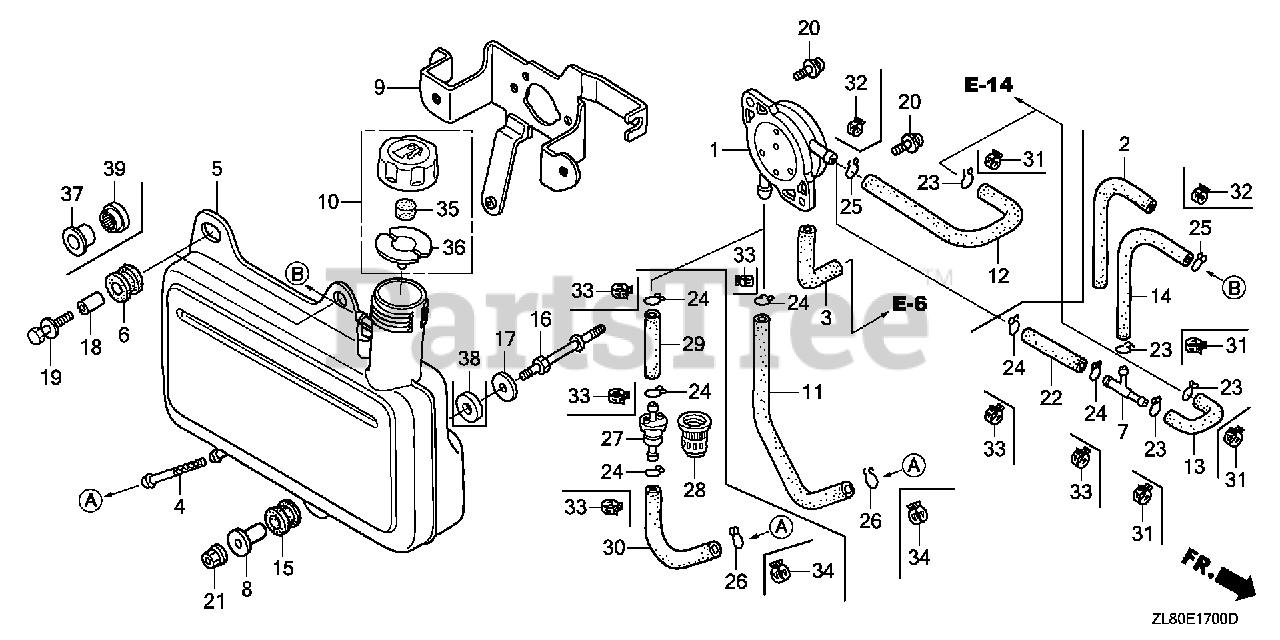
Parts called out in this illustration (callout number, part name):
1	PUMP ASSY., FUEL
3	TUBE, DIAPHRAGM
4	FILTER, FUEL
5	TANK, FUEL
6	RUBBER B, TANK MOUNTING
8	COLLAR, FUEL TANK SETTING
9	STAY A, FUEL TANK
10	CAP ASSY., FUEL TANK
11	TUBE, FUEL TANK
12	TUBE, FUEL
15	CUSHION, RR. FENDER
16	BOLT, FUEL TANK STUD (H=30MM)
17	WASHER (6MM)
18	COLLAR (14X6.1)
19	BOLT-WASHER (6X25)
20	SCREW-WASHER (5X14)
21	NUT, FLANGE (6MM)
23	CLIP, TUBE (B8)
24	CLIP, TUBE (B10)
25	CLIP, TUBE (C9)
26	CLIP, TUBE (C11)
31	CLIP, TUBE (D8)
32	CLIP, TUBE (D8.5)
33	CLAMP, TUBE (D10)
34	CLAMP, TUBE (D12)
35	SPONGE, FUEL CAP BREATHER
36	GASKET, FUEL CAP
